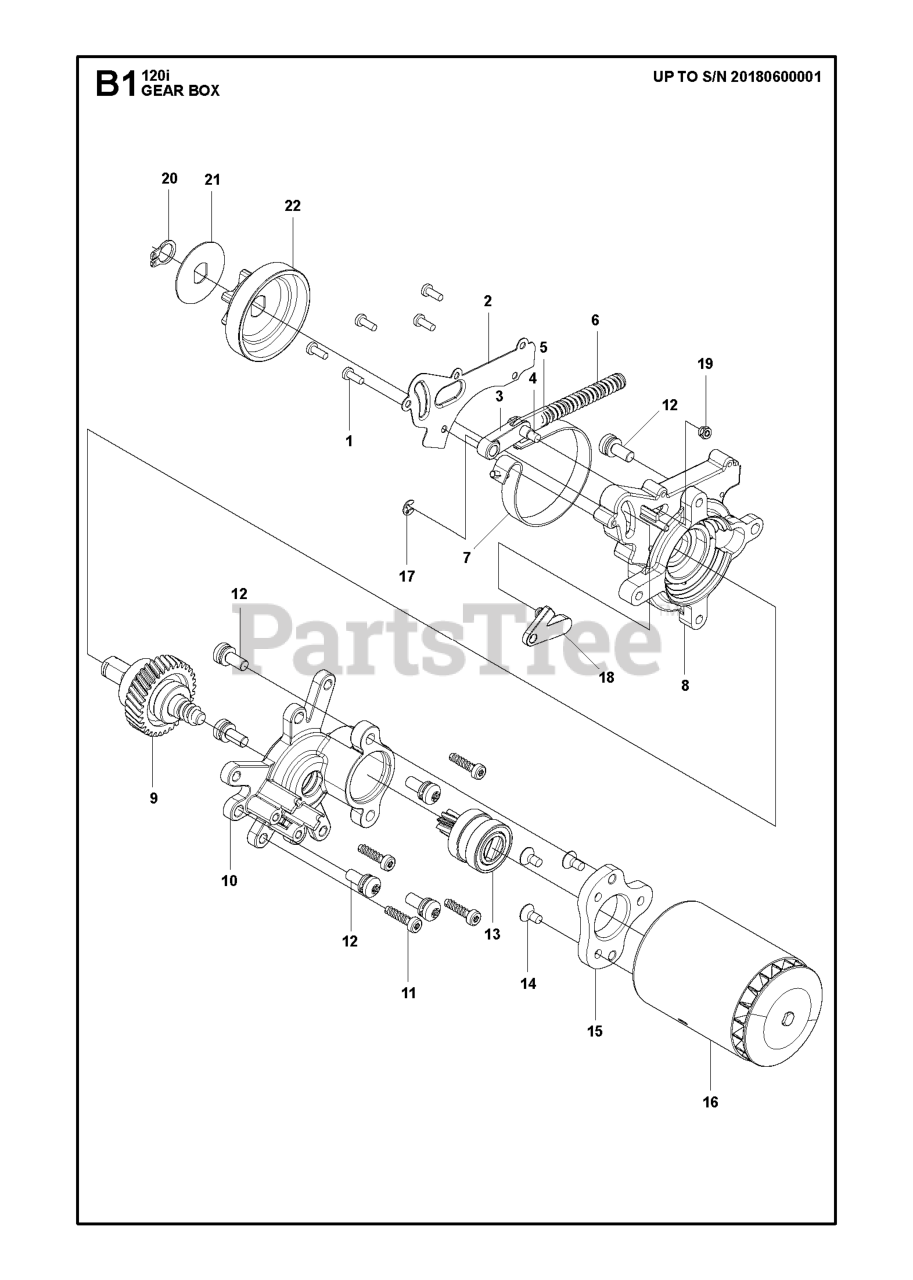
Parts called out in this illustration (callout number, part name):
1	SCREW M3X8 MACHINE SCREW
2	COVER PLATE BRAKE
3	PLATE JOINT
4	PEN BRAKE SYSTEM
5	PLATE BRAKE
6	BRAKE SPRING
7	BRAKE BAND
8	GEARBOX BOTTOM 36V
9	SHAFT ASSEMBLY
10	GEARBOX TOP
11	SCREW ST4X16
12	SCREW M5X13TOR X MACHINING SCR
13	PINION ASSEMBLY
14	SCREW SUNK M4X8
15	CONNECTOR MOTOR
16	MOTOR BLDC
17	CLAMP FOR BRAKE SYSTEM
18	DRIVE LINK DRIVE LINK
19	NUT LOCKING NUT
22	SPROCKET CHAIN 6 TOOTH
